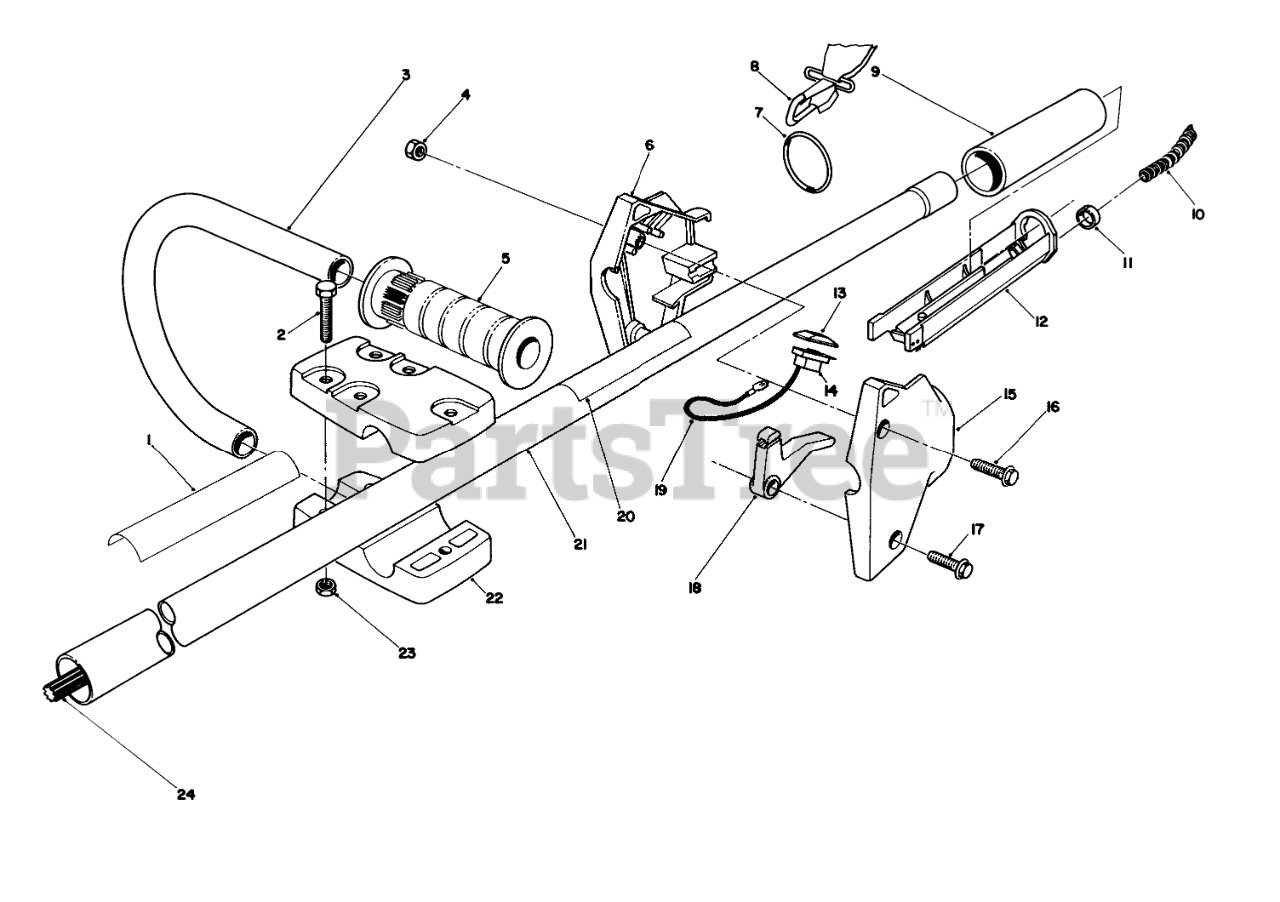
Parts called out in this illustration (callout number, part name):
1	Decal-TC 4000
2	SCREW-HH
3	Tube-Handle
4	NUT-LOCK, NI
5	LH GRIP
6	THROTTLE HSG.R H
7	RING-HARNESS
8	Harness
9	GRIP - RUBBER
10	Cover-Cable
11	RING FITTING
12	TROUGH 1"
13	SWITCH COVER-BLACK
14	SWITCH
15	THROTTLE HSG. L H
17	SCREW-HWH
18	THROTTLE LEVER
19	WIRE ASM
20	Decal
21	TUBE ASSEMBLY
22	CLAMP
23	NUT-LOCK, NI
24	SPLINED SHAFT
